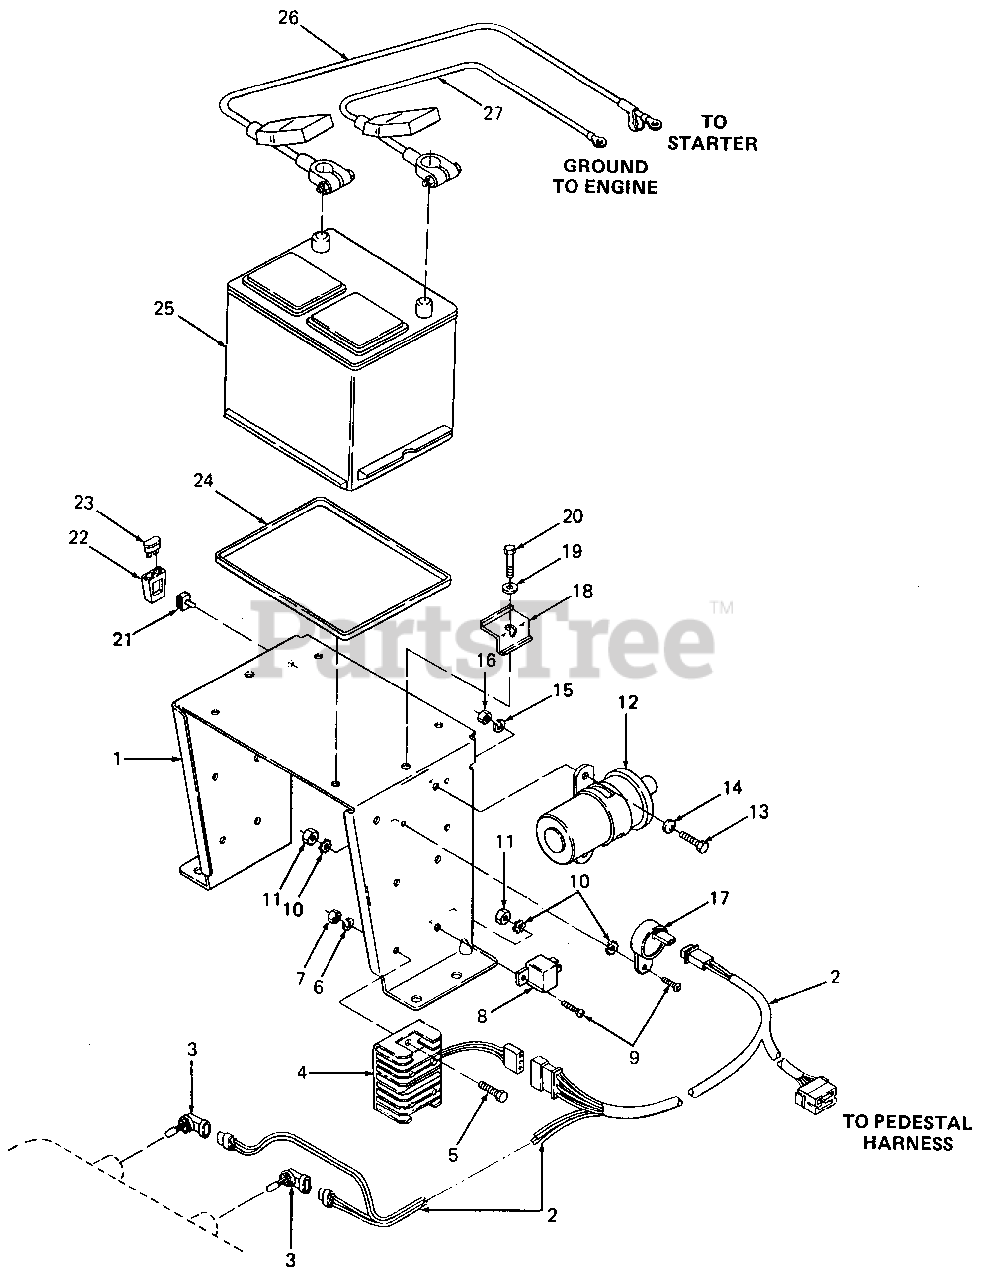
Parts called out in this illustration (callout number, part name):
1	Tray Assy, Battery
2	Harness, Main
3	Bulb, Head Lamp
4	Rectifier
5	Screw, Hex Cap, 1/4-20 X 1.25 Lg
6	Washer, Lock, 1/4
7	Nut, Hex, 1/4-20 GR5
8	Relay
9	Screw, Truss Mach, #10-24 X .50 Lg
10	Washer, External, #10
11	Nut, Hex, #10-24
12	Coil, Ignition
13	Screw, Hex Cap, 5/16-18 X .75 Lg GR5
14	Washer, Bell, .345 X .88 X .060 Thk
15	Washer, Lock, 5/16
16	Nut, Hex, 5/16-18 GR5
17	Indicator, Voltage
20	Screw, Hex Cap, 5/16-18 X 2.0 Lg
21	Clip, Fuse Holder Mtg
22	Holder, Fuse
23	Fuse, 20 Amp
24	Tray, Battery
25	Battery
26	Cable, Positive Battery
27	Cable, Negative Battery
